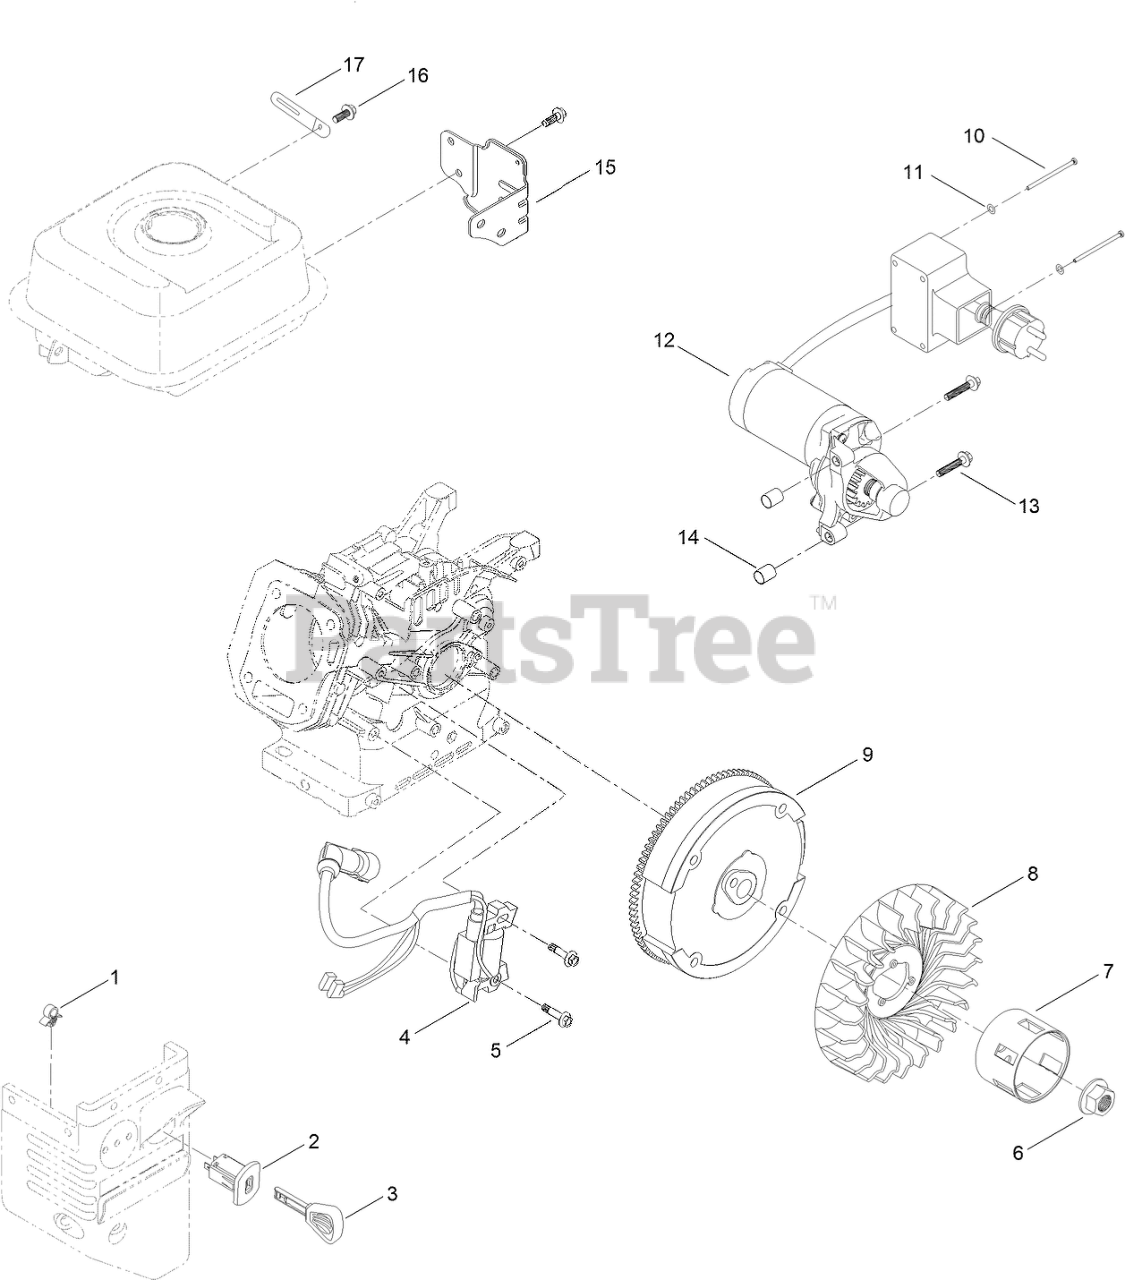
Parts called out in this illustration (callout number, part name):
2	SWITCH-KEY
4	IGNITION COIL ASM
5	SCREW-HHF
6	NUT-FLANGE
7	CUP-STARTER
9	FLYWHEEL
10	SCREW-BHP
11	WASHER-PLAIN
12	MOTOR-STARTER
13	SCREW-FLANGE
14	PIN-DOWEL
15	BRACKET-BOX, SWITCH
16	SCREW-HHF
17	CLIP-HARNESS, WIRE
